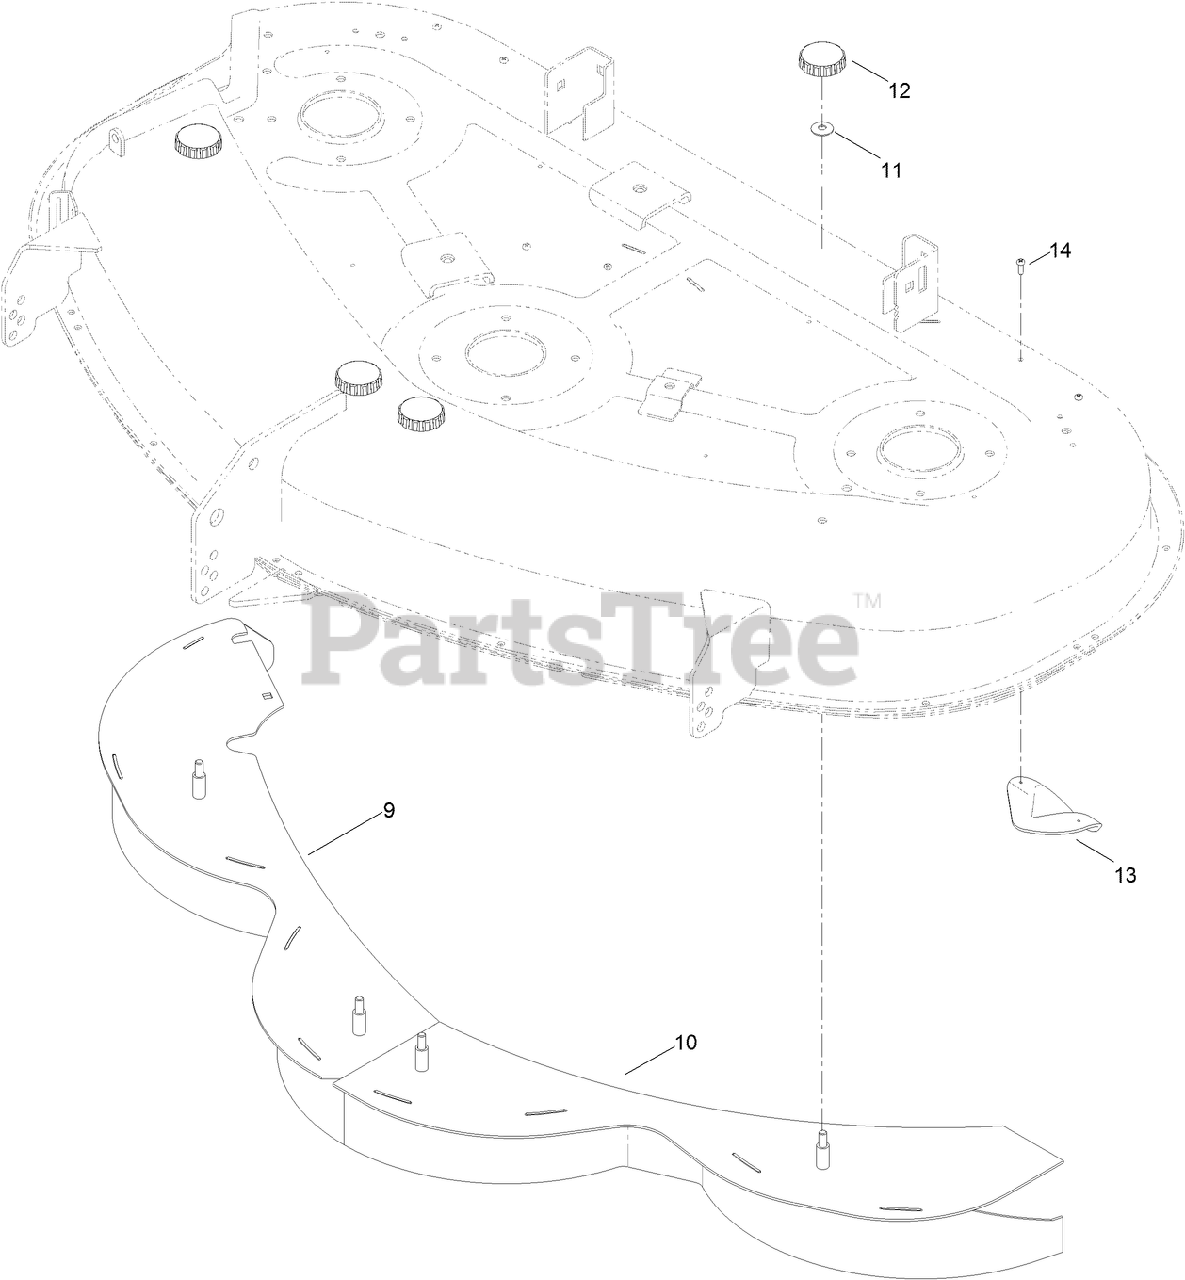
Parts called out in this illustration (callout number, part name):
9	RH BAFFLE ASM
10	LH BAFFLE ASM
11	WASHER-BELLEVILLE
13	PLATE-KICKER
14	SCREW-PPH
